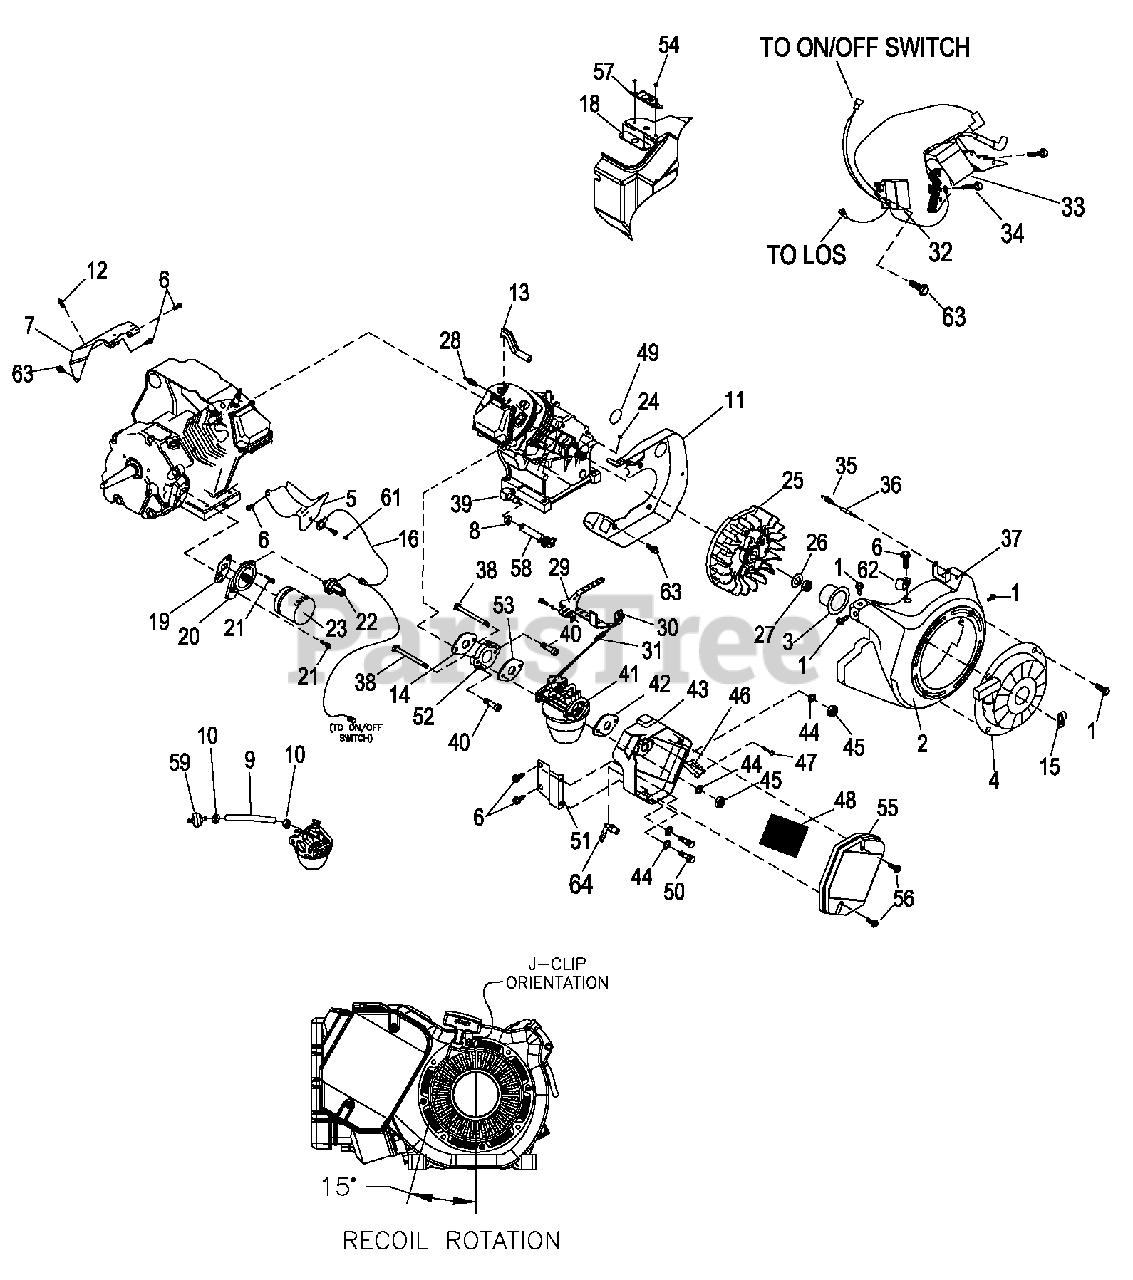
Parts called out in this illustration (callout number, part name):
1	SCREW HHTT M6-1.0 X 8 ZYC
2	ASSEMBLY, BLOWER HOUSING
3	PULLEY STARTER LARGE FRAME
4	RECOIL STARTER LARGE FRAME
5	WRAPPER, BOTTOM 12 HP HS
6	SCREW HHTT M6-1.0 X 10 YELLOW CHROME
7	WRAPPER, TOP REGULAR STEEL
8	CLAMP,HOSE OETIKER STPLSS 18.5
9	FUEL HOSE, 250 MM LONG
10	CLAMP HOSE BAND .41
11	BACKPLATE
12	SCREW, HHTT 5/16-18X1/2" CLEAR
13	HOSE, BREATHER GH410 ENGINES
14	GASKET, INTAKE ADAPTER
15	CLIP-J, VINYL COAT
16	WIRE HARNESS, 410 ENGINE SWITCH WIRING
17	BARBED EL
18	BACK PLATE, SUPPORT
19	GASKET,OIL FILTER ADAPTER
20	ADAPTER, OIL FILTER
21	SCREW, SHC M8-1.25 X 30 G12.9
22	SWITCH, HOBBS OIL PRESSURE 5PSI
23	FILTER, OIL BLACK 75 LONG
24	KEY, WOODRFF 4 X 19D
25	FLYWHEEL, LARGE FRAME 27 DEG
26	WASHER,BELV-20 X 2.2
27	NUT HEX M20-1.5 G8 YLW CHROME- FLYWHEEL
28	SPARKPLUG, CHAMPION RC14YC 0.030"
29	ASSEMBLY,GOVERNOR LEVER 12HP
30	ROD, GOVERNOR CONTROL
31	SPRING, ANTI-LASH
32	OIL PRESSURE SHUTDOWN MODULE
33	ASSEMBLY, IGNITION ADV NO DIODE GH410
34	SCREW HHFC M6-1.0 X 25 G8.8
35	SPRING GOVERNOR 320/360/410
36	BOLT, GOVERNOR ADJUSTMENT M5
37	NUT, HEX LOCK M5-0.8 NYLON INSERT ZINC
38	BOLT, CARBURETOR MOUNTING
39	BARBED ELBOW 90 DEG 3/8" NPT X 3/8"
40	FLANGE HEAD SCREW, SHC M6-1.0 X 20 G8.8ZP
41	CARBURETOR ASSEMBLY, 410HS
42	GASKET, AIR CLEANER
43	BASE, AIR CLEANER 410 HI FLOW XP PORT
44	WASHER, FLAT M6
45	NUT, HEX LOCK M6-1.0 NYLON INSERT
46	PLATE, SPITBACK
47	SCREW HWHTF 8-18 X 0.5 HI-LOW
48	ELEMENT, AIR FILTER
49	PLUG PLASTIC 1.875
50	SCREW, HHC M6-1.0 X 16 W/ LOCK WASHER
51	BRACKET, AIR CLEANER
52	ADAPTER, "K"
53	GASKET, CARBURETOR/MANIFOLD
54	RIVET, 1/8"
55	COVER, AIR CLEANER 13GN
56	BOLT, AIR CLEANER COVER
57	BRACKET, CHOKE CABLE
58	ASSY OIL DRAIN HOSE, 6" LONG ORANGE
59	FUEL FILTER
61	GROMMET
62	C-CLIP STL/VNL .437 X .281
63	SCREW HHFC M6-1.0 X 12
64	BARBED EL
